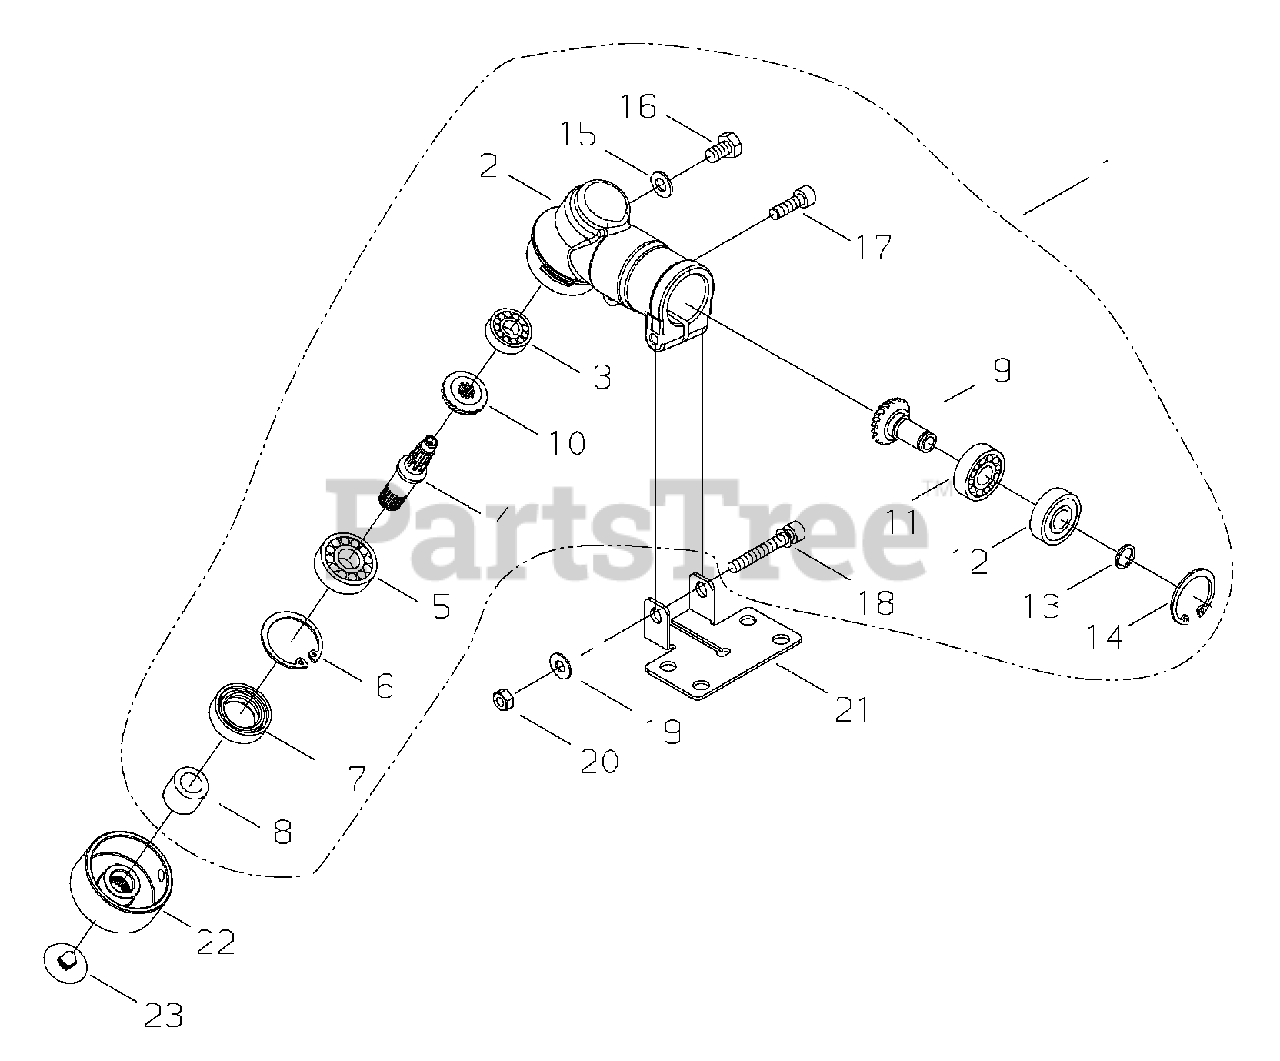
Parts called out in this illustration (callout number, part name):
1	GEAR CASE ASSY
2	HOUSING, GEAR CASE
3	BEARING, BALL 626 MOS
4	SHAFT, GEAR
5	BEARING, BALL 6000 MOS
6	RING, SNAP Ø26
7	SEAL, OIL
8	SPACER
9	GEAR, PINION
10	GEAR, BEVEL
11	BEARING, BALL 609 MOS
12	BEARING, BALL 609Z MOS
13	RING, SNAP Ø9
14	RING, SNAP Ø24
15	WASHER 6.5×11.5×0.8
16	BOLT M6×10
17	BOLT M5×10
18	BOLT M5×40
19	WASHER 5 MM
20	NUT M5
21	PLATE, SHIELD MOUNTING
22	HOLDER
